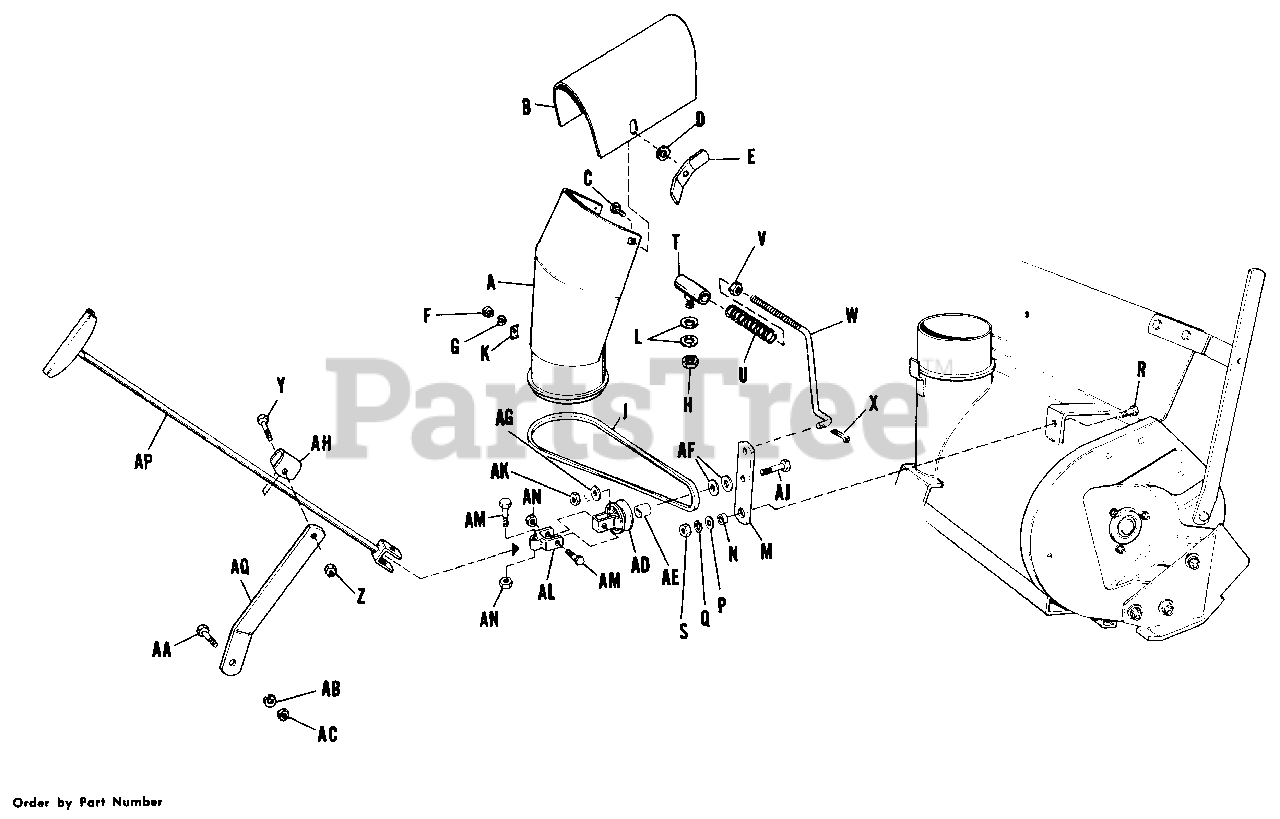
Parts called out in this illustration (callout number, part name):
A	Spout Assembly
B	Extension, Spout
C	Carriage Bolt, 5/16"-18 NC x 3/4" lg.
D	Washer, Plain, 3/8"
E	NUT, Wing, 5/16-18
F	Nut, Hex, Full, 5/16"-18 NC
G	Washer, Lock, 5/16"
H	Nut, Lock, Full, Hex, 5/16"-18 NC
J	Belt, "V"
K	Clamp, Spout Cord
L	Washer, Plain, 5/16"
M	Lever, Idler Pulley
P	Washer, Plain, 3/8"
Q	Washer, Lock, 3/8"
R	Capscrew, Hex Hd., 3/8"-16 NC x 1" lg.
S	Nut, Hex, Full, 3/8"-16 NC
T	Socket Assembly, Rod
V	Nut, Hex, Full, 3/8"-16 NC
W	Rod, Belt Tightener
X	Pin, Cotter, 3/32" x 3/4" lg.
Y	Capscrew, 5/16"-18 NC x 1 1/4" lg.
Z	Nut, Hex, Full Lock, 5/16"-18 NC
AA	Capscrew, Hex Hd., 3/8"-16 NC x 1" lg.
AB	Washer, Lock, 3/8"
AC	Nut, Hex, Full, 3/8"-16 NC
AD	Pulley Assembly, Idler
AG	Washer, Plain, 3/8"
AJ	Capscrew, Hex Hd., 3/8"-16 NC x 1 3/4" lg.
AK	Nut, Hex, Full, 3/8"-16 NC
AL	Fork Assembly
AM	Capscrew, Hex Hd., 5/16"-18 NC x 1 1/2" lg.
AN	Nut, Hex, Full Lock, 5/16"-18 NC
AP	Handle Assembly
AQ	Support, Rod Guide
